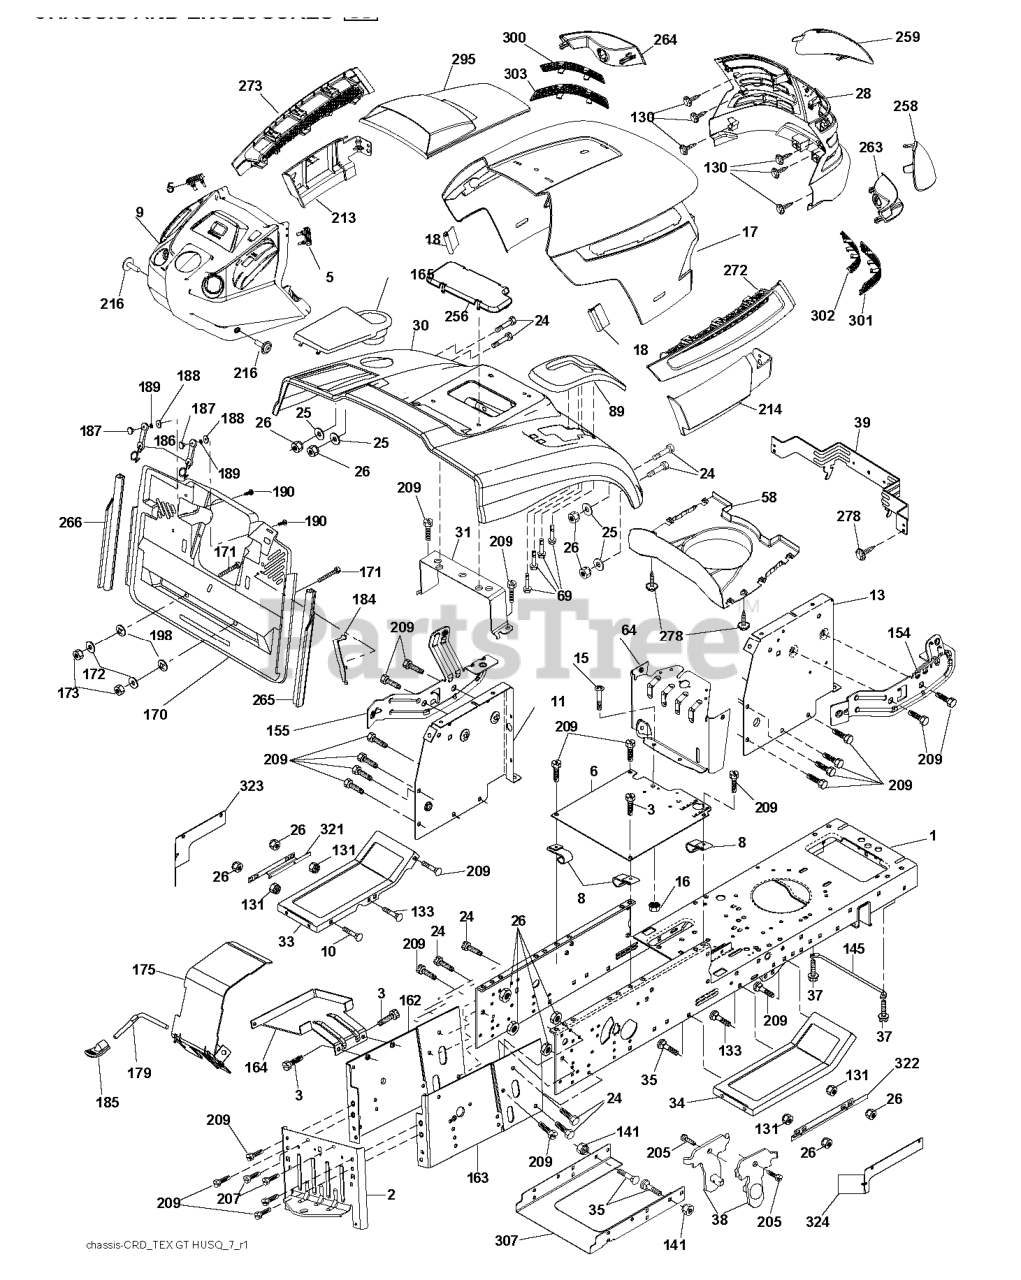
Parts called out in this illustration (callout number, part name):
2	DRAWBAR
3	SCREW 3/8-16X3/4
5	BUMPER DASH
6	PLATE
8	CLIP,INSULATOR
10	BOLT.3/8-14X1.25
11	PANEL DASH LH
13	PANEL DASH RH
15	Screw, Machine, Truss Head 5/16-18 UNC x 3/4
16	NUT
17	HOOD
18	BUMPER.HOOD.TEX.HUSQVARNA
25	WASHER
26	NUT
28	GRILL.ASM.HUSQ.TG/CRD.W/TRIM
30	CONSOLE.CRD.AUTO.GRY
31	BRACKET SUPPORT FENDER
33	FOOTREST PNT LH
34	FOOTREST PNT RH
37	Screw 5/16-18 x 1/2 Hex, Self Tapping 5/16-18 x 1/2
38	BRACKET ASM PIVOT MOWER REAR
39	HOOD PIVOT BRACKET
58	AIR.DUCT.TEXGT.HUSQ.31
69	SCREW.HI-LO.CONSOLE
89	CONSOLE.CRD.AUTO.GREY.2005
131	NUT.HEX.3/8-16UNC
133	BOLT D
141	NUT LOCK FLG 3/8-16 UNC
145	ROD.PIVOT.HOOD
162	BRACKET
163	BRACKET EXTEN CHASSIS RH CRD
165	COVER.BATTERY.BGGR.ELE
172	WASHER
175	DOOR TRAP
179	ROD PIVOT FBI
184	BRACKET.ACTUATOR.BAGGER.SRD
186	LATCH ASSY
187	WELDNUT
189	LOCKWASHER #10
190	SCREW
207	SCREW, 5/16-18 X 1/2
209	SCREW, 3/8-16X3/4
213	SKIRT.HOOD.SIDE.HUSQ.LH.GREY
214	SKIRT.HOOD.SIDE.HUSQ.RH.GREY
216	SCREW 14-20 X 5/8
256	COVER FENDER CRD
258	LENS.RH.TEX.GT.HUSQ.CL
259	LENS.LH.TEX.GT.HUSQ.CL
263	BEZEL.RH.TEX.GT.HUSQ
264	BEZEL.LH.TEX.GT.HUSQ
265	SEALING
266	SEALING
272	VENT.SIDE.HOOD.HUSQ.RH.GREY
273	VENT.SIDE.HOOD.HUSQ.LH.GRAY
278	SCREW.#10 X 0.750.BOS
295	HOOD VENT
300	INSERT.HEX.GRILL.HUSQ.
301	INSERT.HEX.GRILL.HUSQ.GREY
302	INSERT.HEX.GRILL.HUSQ.
303	INSERT.HEX.GRILL.HUSQ.
321	SHIELD INNER LEFT
322	SHIELD INNER RIGHT
323	PLATE LEFT
324	PLATE RIGHT
